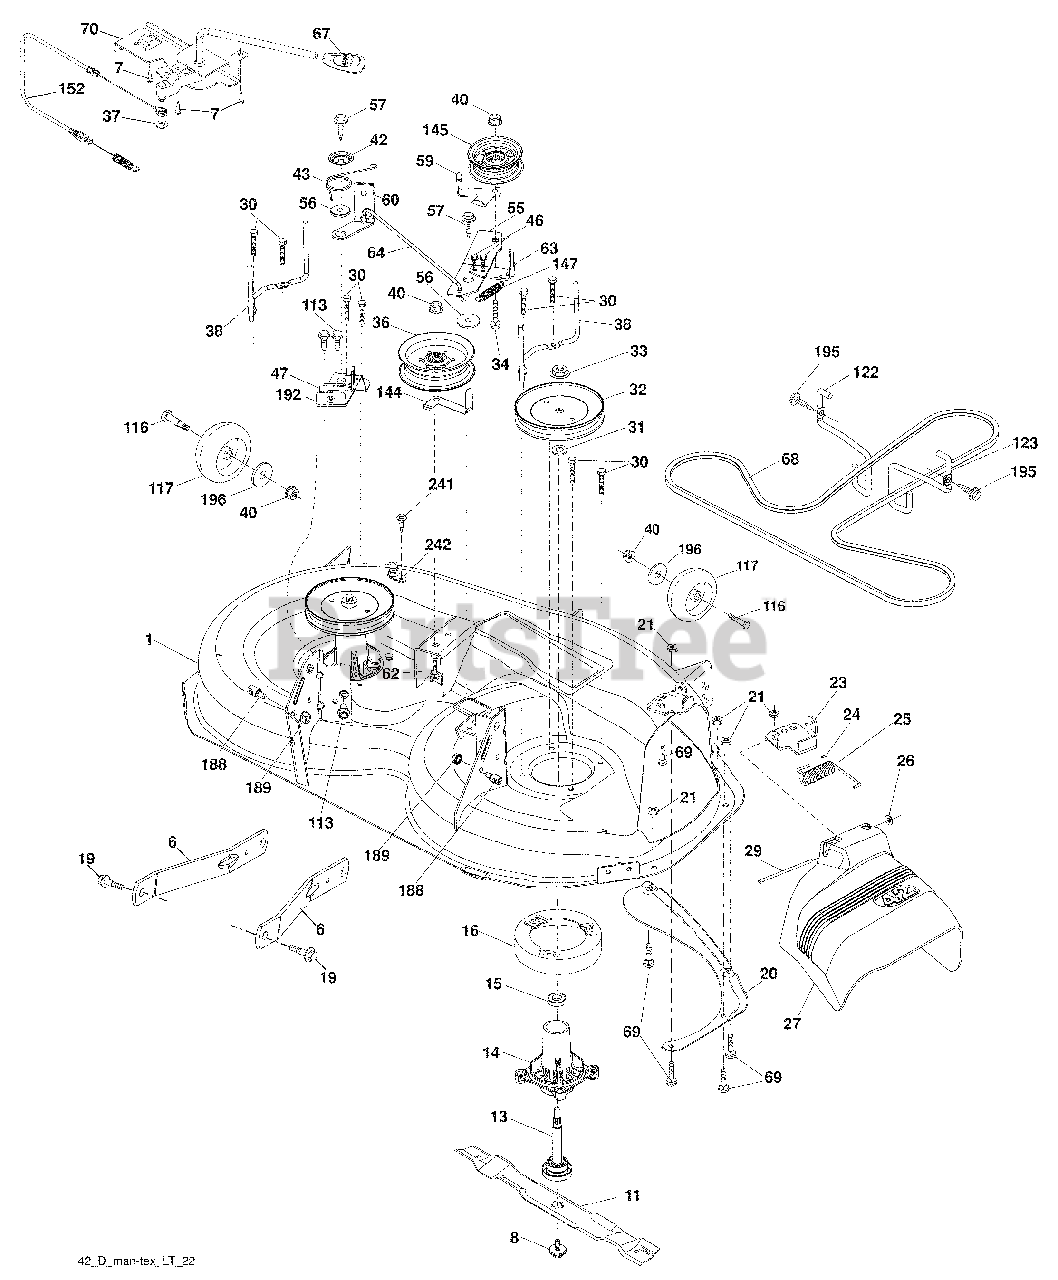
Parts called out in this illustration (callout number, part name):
1	Mower Housing
6	Arm Suspension
7	Screw #10 x 0.750 BOS Thread
8	Bolt/Washer Asm 7/16-20 unf
11	Blade High Lift
13	Shaft Assembly, Mandrel
14	Housing, Mandrel
15	Bearing, Ball, Mandrel
16	Stripper Mandrel
19	Bolt, Shoulder
20	Baffle Vortex
21	Nut
23	Bracket, Deflector
24	Cap, Sleeve
25	Spring, Torsion, Deflector
27	Shield, Deflector
29	Rod, Hinge
30	Screw Thdrol Rolling Wsh Hd
31	Washer, Spacer
32	Pulley, Mandrel
33	Nut, Toplock, Flanged
34	Bolt Carr Sh. 3/8-16 x1-1/2 Gr. 5
36	Pulley, Idler, Flat
37	Washer 13/32 x 13/16 x 16 Ja.
38	Keeper Belt LH Mandrel
40	Nut, Lock Flg. 3/8-16 unc
42	Spring Torsion Retainer
43	Spring Torsion Brake
46	Screw Thd Roll 1/4-20 x 5/8
47	Bracket Clutch Cable
55	Arm, Idler
56	Spacer, Retainer
57	Screw Hexwsh Thd 3/8-16 x 1
59	Guard, Tuv Idler (94)
60	Arm Brake Mower
62	Bolt 3/8-16 unc x 2
63	Arm Brake Mower
64	Linkage Brake
67	Handle Clutch Cable
68	V-Belt
69	Bolt
70	Clutch Asm Cable
113	Screw 5/16-18
116	Bolt, Shoulder
117	Wheel, Gauge
122	Keeper Belt Engine LH
123	Keeper Belt Engine RH
144	Keeper Belt Mower
145	Pulley Idler
147	Spring Return
152	Cable Clutch CBL w/Spr
188	Stud Fastener
189	Nut Lock Hex Flange
192	Bracket Brake Stand LH
195	Screw Hexwsh Thdr 3/8-16 x 3/4
241	Screw TT #10-32.5.3/8 Flange
242	Washout Port
